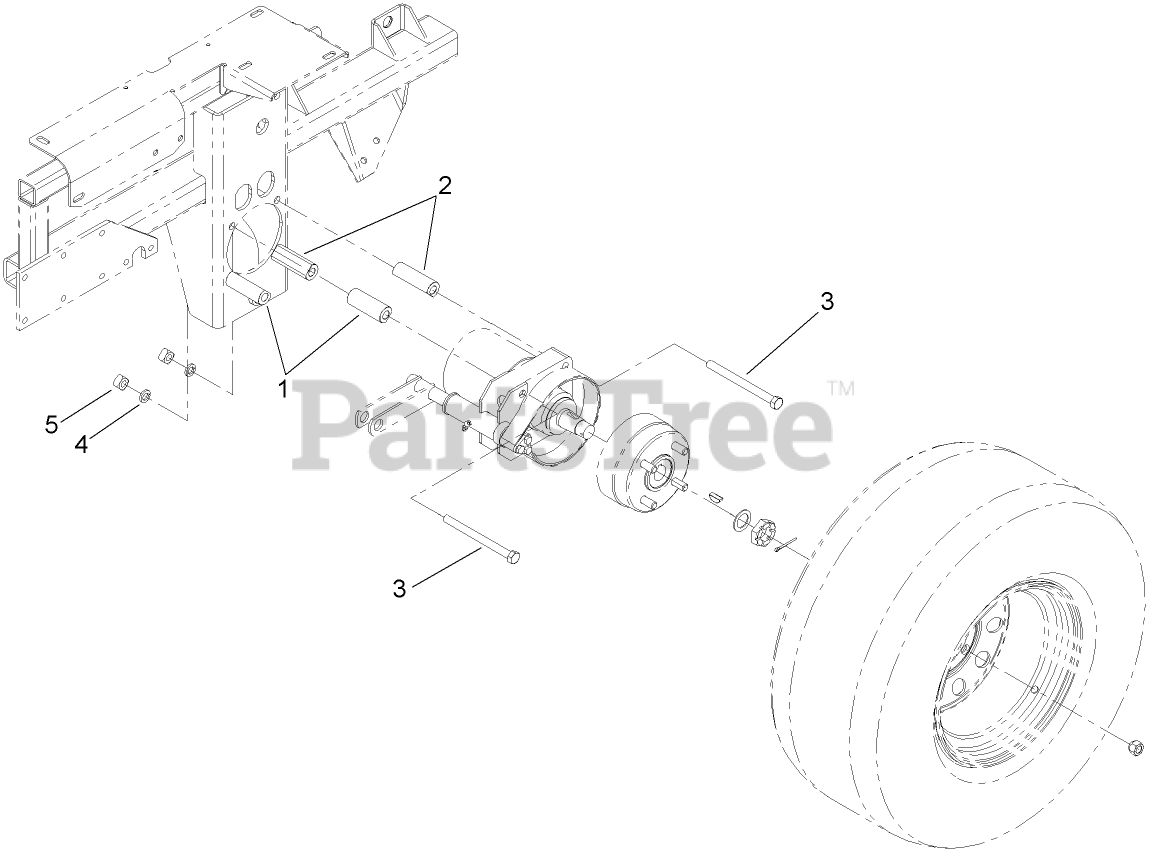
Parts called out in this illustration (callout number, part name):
1	SPACER-WHEEL, SHORT
2	SPACER-WHEEL, LONG
3	SCREW-HH
4	WASHER-LOCK
5	NUT-SQUARE
